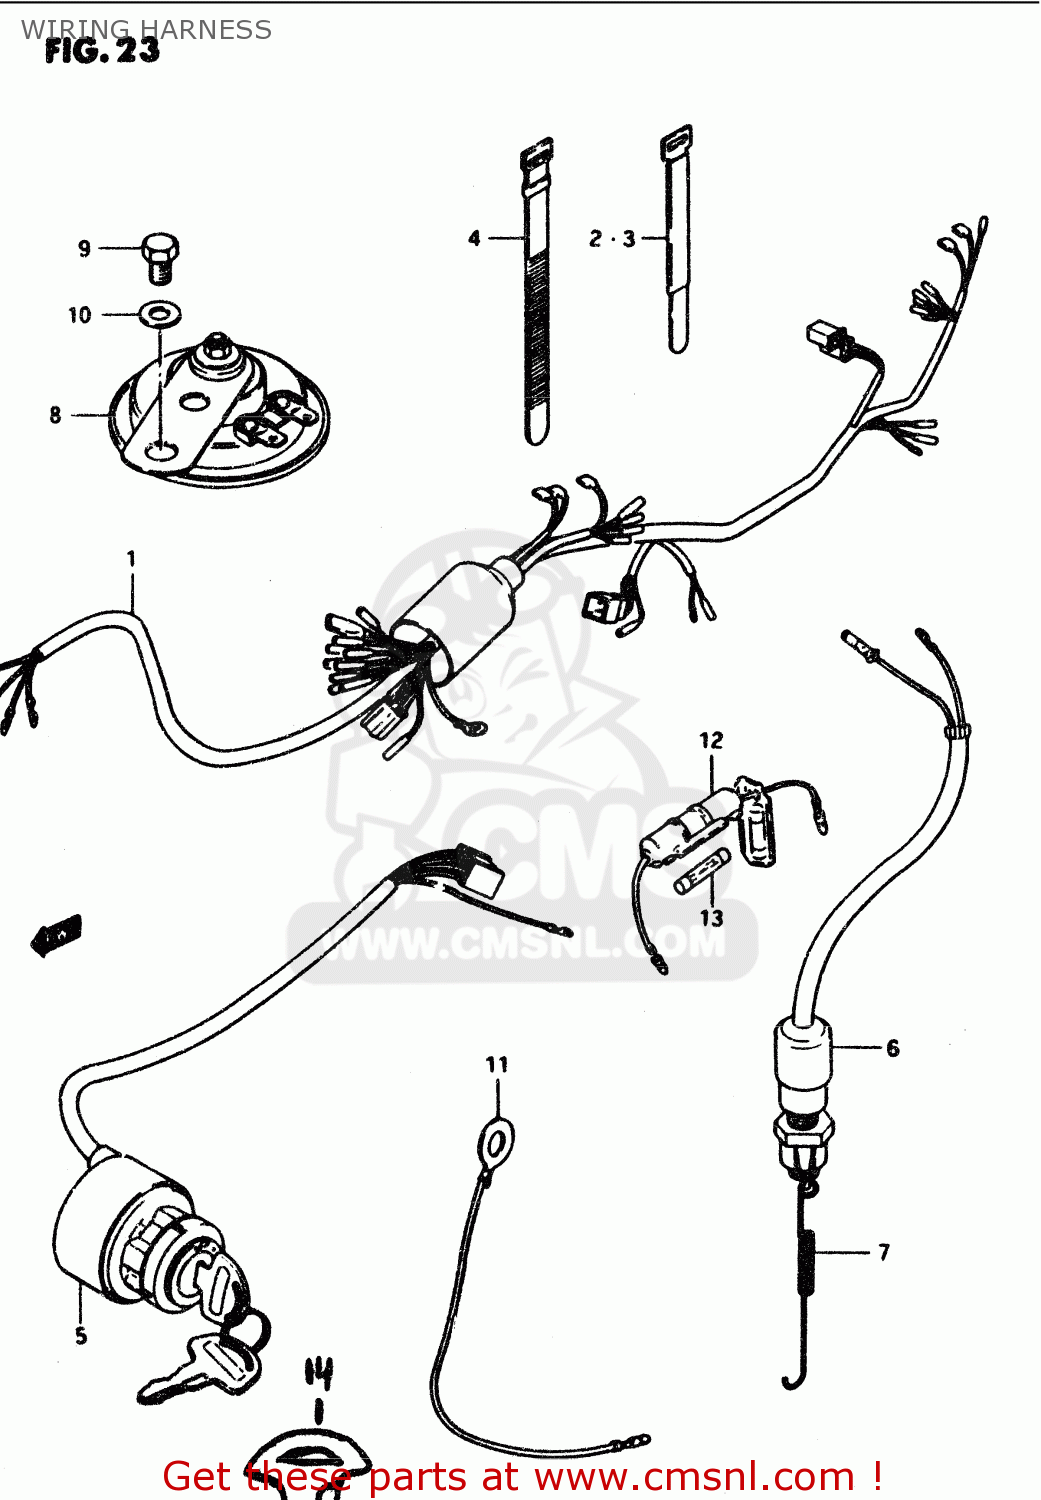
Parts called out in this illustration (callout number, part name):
1	WIRING HARNESS
2	CLAMP
3	CLAMP
4	CLAMP L:165
5	SWITCH ASSY,IGNITION
6	SWITCH ASSY,STOP LAMP
7	SPRING
8	HORN ASSY
9	BOLT
10	WASHER
11	LEAD WIRE,EARTH
12	CASE ASSY,FUSE
13	FUSE(10A)
14	KEY,BLANK
